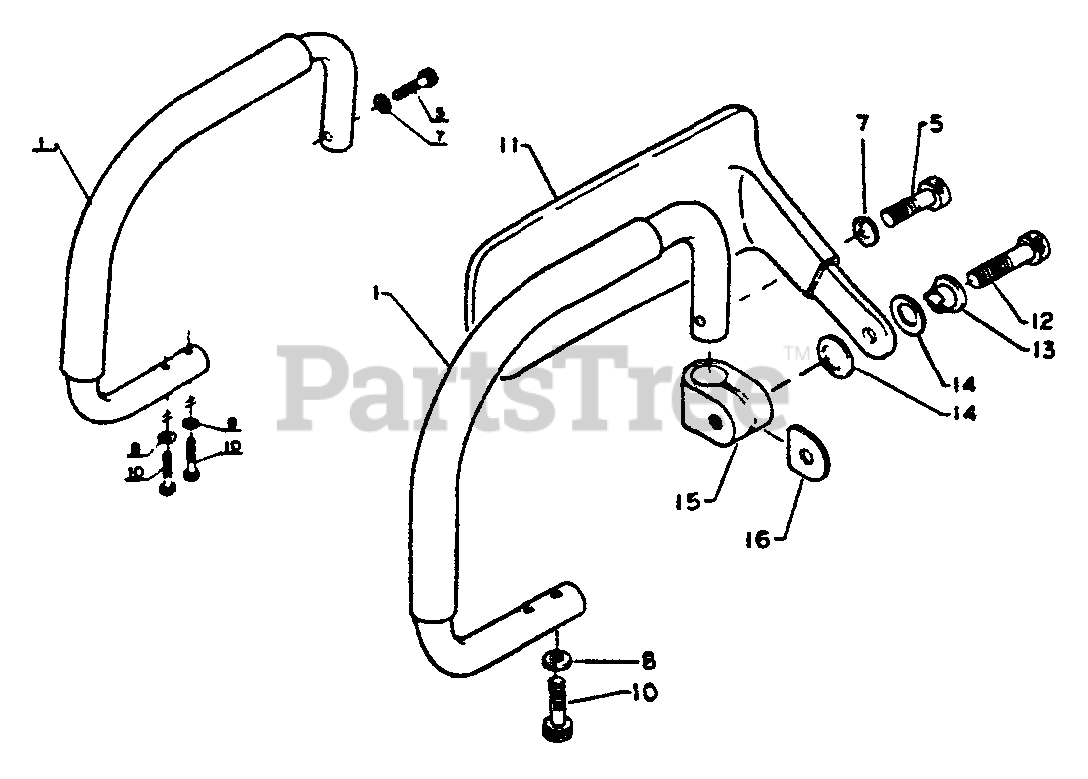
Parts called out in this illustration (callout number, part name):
1	HANDLE - FRONT
5	SCREW - 5X20
7	WASHER - 5
8	WASHER - 4
10	SCREW - 4X18
11	GUARD
12	SCREW - 5X30
14	WASHER - CONICAL
15	HOLDER
